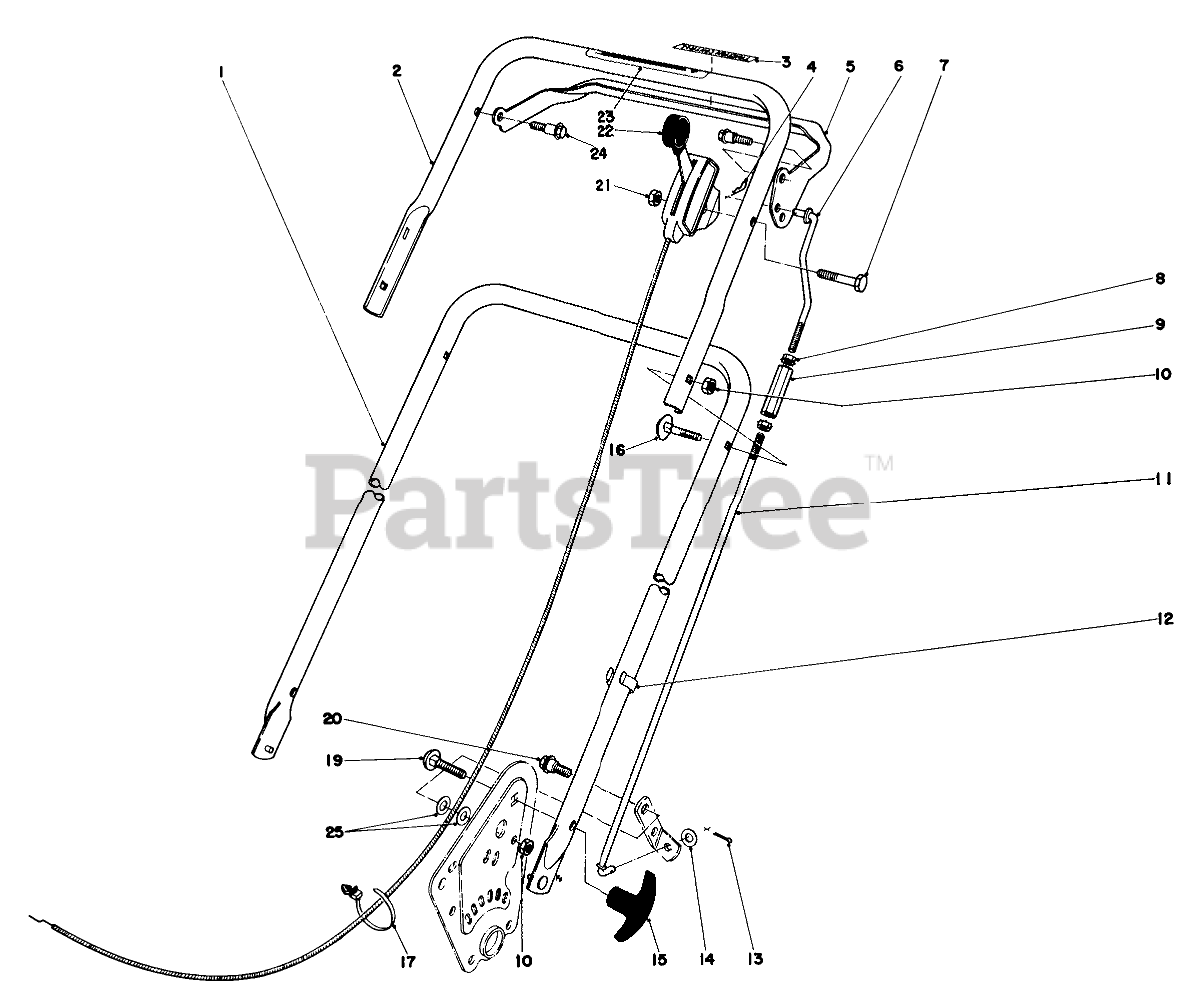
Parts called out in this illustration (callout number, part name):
1	Lower Handle
2	Upper Handle
3	Decal-Traction Control
4	PIN-COTTER
5	Squeeze Lever
6	CONTROL ROD LINK
7	SCREW-HH
8	NUT-KEPS
9	CONTROL ROD SLEEVE
10	Nut
11	CUTTER CONTROL ROD
13	PIN-COTTER
14	WASHER-PLAIN
16	HANDLE SCREW
17	TIE-MOUNT, PUSH
19	BOLT-CARR
20	SCREW-SHOULDER
21	NUT-LOCK
22	Throttle Control
23	Decal
24	Shoulder Bolt
25	WASHER-FLAT
